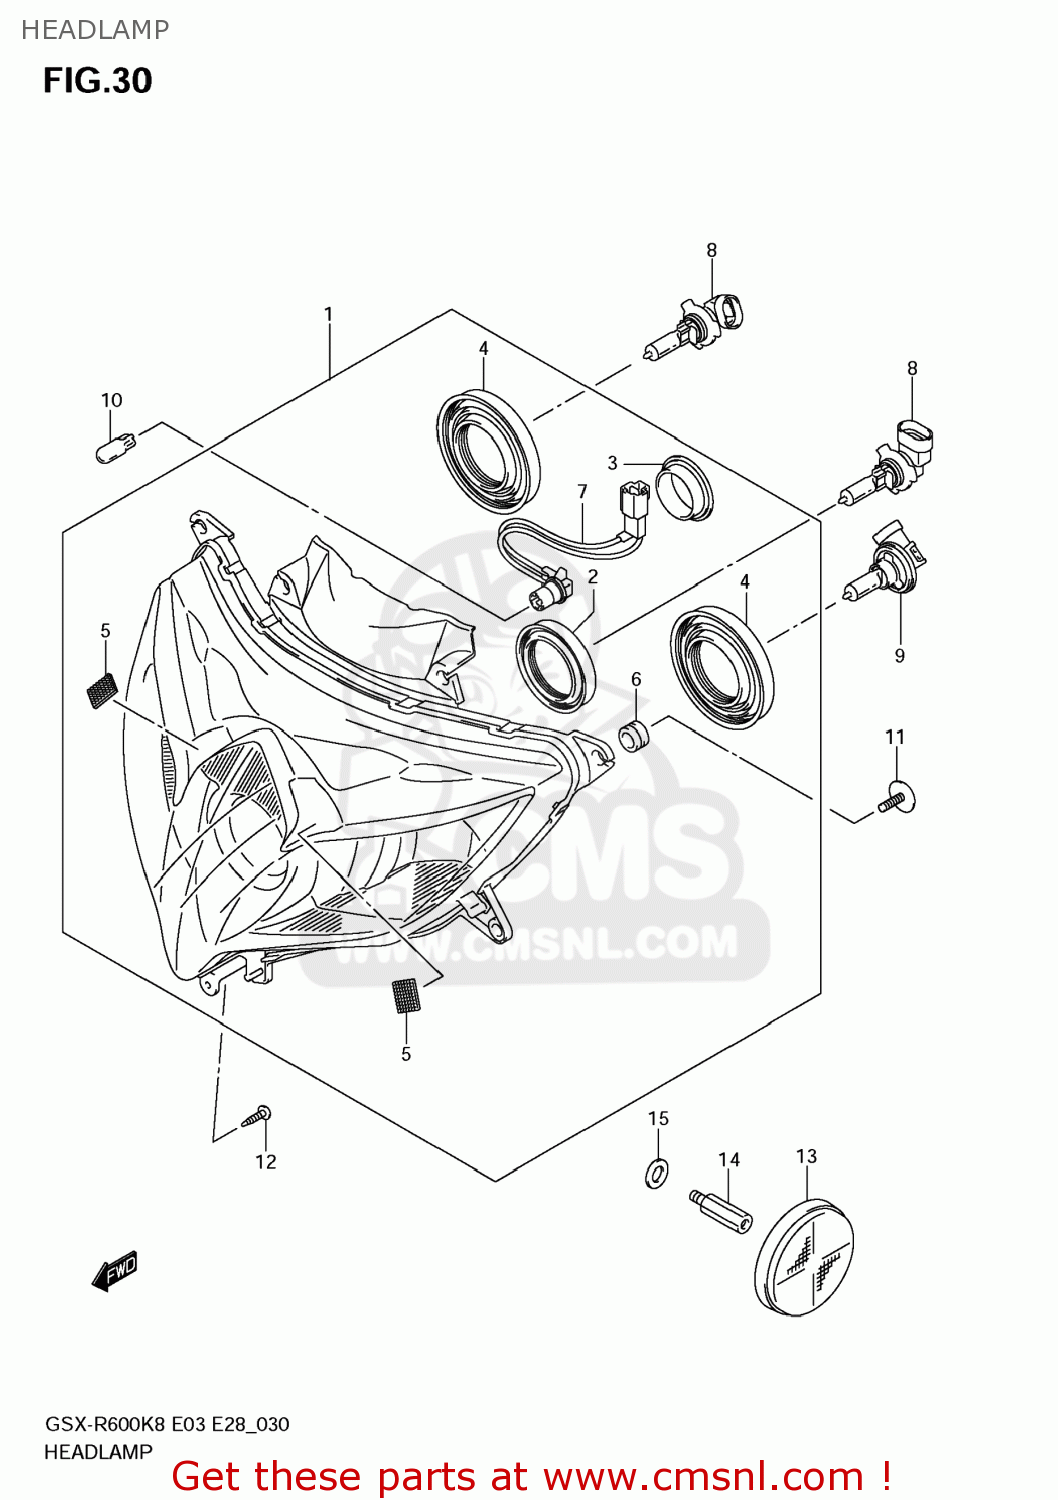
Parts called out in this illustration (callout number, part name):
1	HEADLAMP ASSY
2	COVER,SOCKET
3	COVER,BACK
4	COVER,SOCKET
5	FASTENER,COWLING
6	CUSHION
7	SOCKET & LEAD
8	BULB(12V60W,HB3,#9005)
9	BULB(12V55W,H11)
10	BULB(12V5W)
11	SCREW(5X15)
12	SCREW
13	REFLECTOR,REFLEX
14	BOLT
15	WASHER(8.5X14X1.6)
